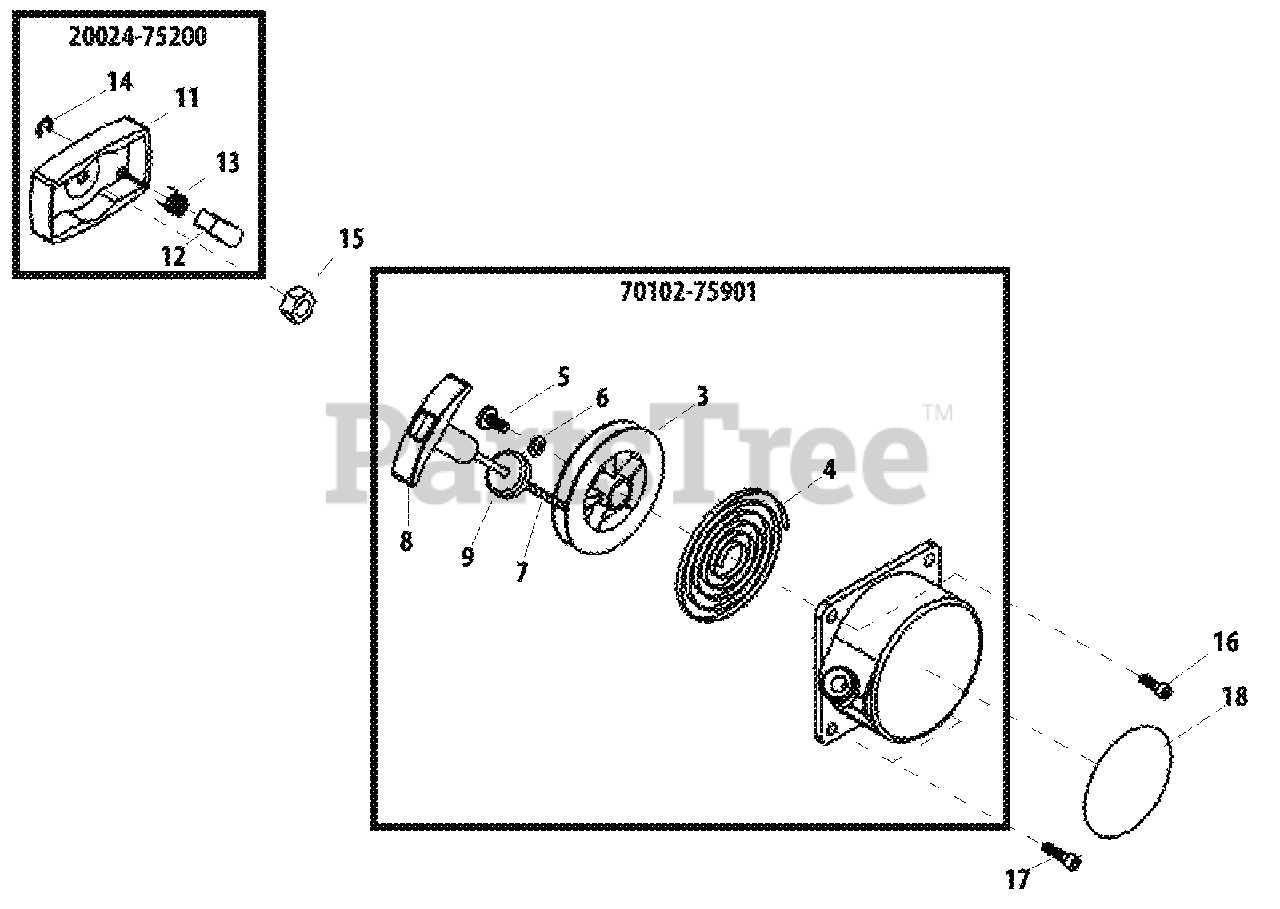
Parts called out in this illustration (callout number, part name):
3	REEL, ROPE
4	SPRING, RECOIL
5	SCREW 5
6	WASHER
7	ROPE, STARTER
8	GRIP, STARTER
9	DAMPER
11	PULLEY, STARTER
12	PAWL, STARTER
13	SPRING, RETURN
14	E-RING 4
15	NUT
16	BOLT M5×16
17	BOLT M5×25
18	LABEL, TRADE
2002475200	PULLEY ASSY, STARTER
7010275901	STARTER ASSY
